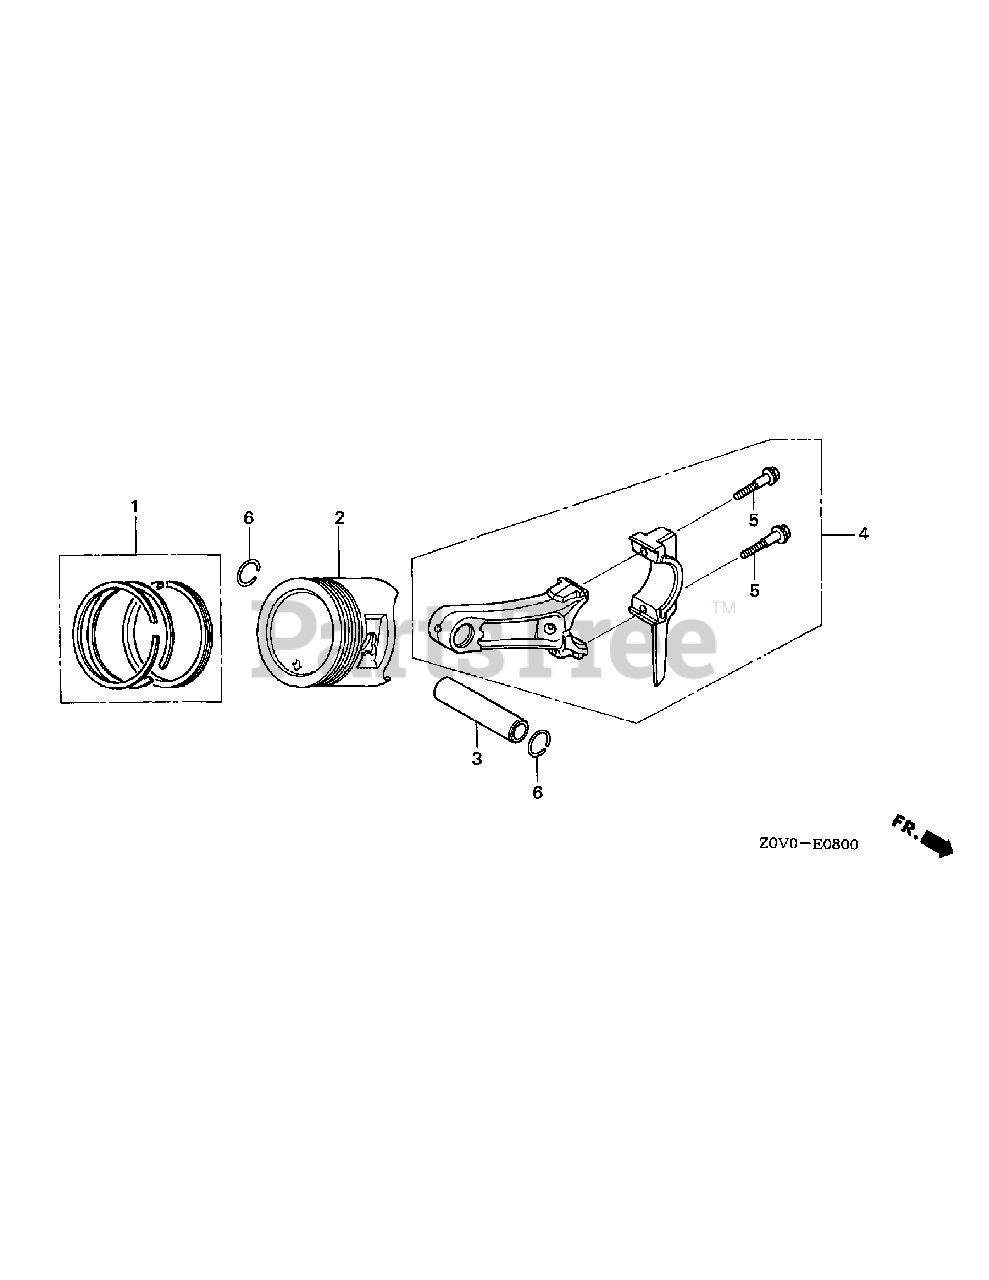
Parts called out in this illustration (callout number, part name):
1	Ring Set, Piston(Std.)(Teikoku)
1	Ring Set, Piston(Std.)(Riken)
1	Ring Set, Piston(0.25)(Teikoku)
1	Ring Set, Piston(0.25)(Riken)
1	Ring Set, Piston(0.50)(Teikoku)
1	Ring Set, Piston(0.50)(Riken)
1	Ring Set, Piston(0.75)(Teikoku)
1	Ring Set, Piston(0.75)(Riken)
2	Piston(Std.)
2	Piston(0.25)
2	Piston(0.50)
2	Piston(0.75)
3	Pin, Piston
4	Rod Assy., Connecting
5	Bolt, Connecting Rod
6	Clip, Piston Pin, 18Mm
